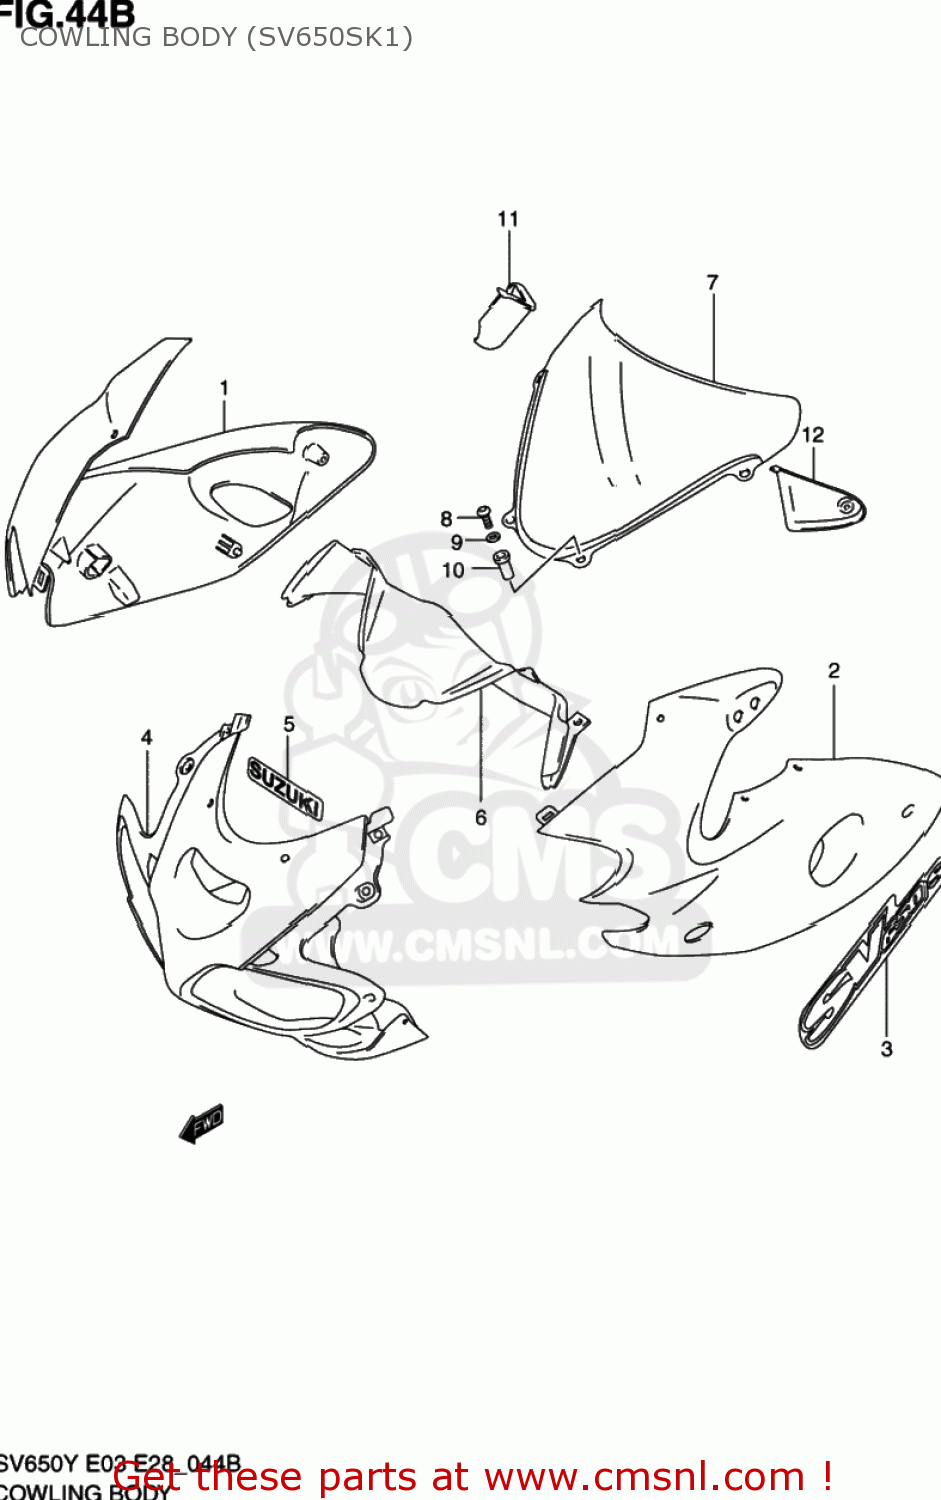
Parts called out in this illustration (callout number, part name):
1	COWLING ASSY,SIDE,R
2	COWLING ASSY,S
3	EMBLEM,COWLING SIDE
4	COWL ASSY CTR
5	EMBLEM,SUZUKI
6	PANEL,METER
7	WINDSCREEN
8	SCREW(5X14)
9	WASHER
10	NUT
11	PANEL,UPR,R
12	PANEL,UPR,L
